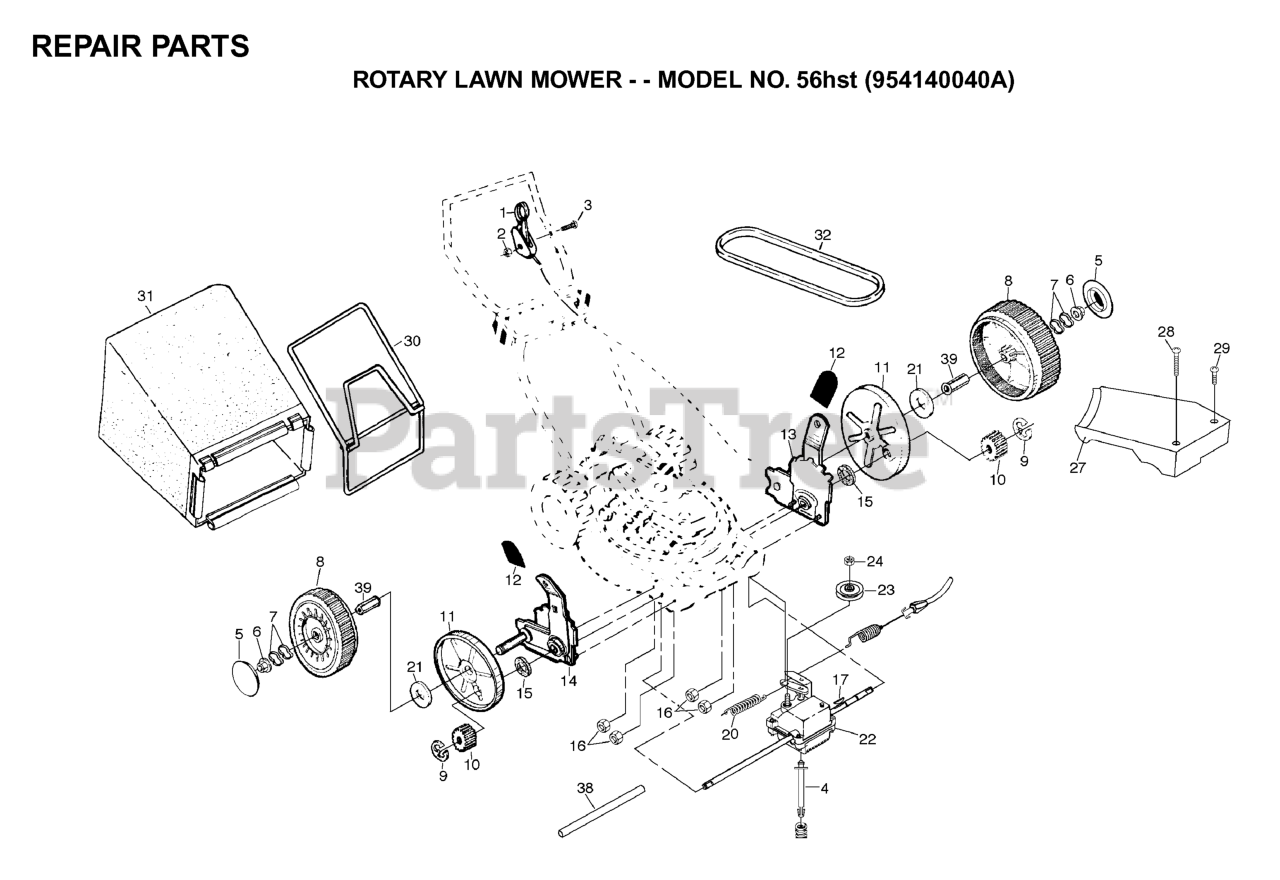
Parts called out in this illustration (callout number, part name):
1	DRIVE CONTROL
2	NUT
3	SCREW 1/4-20 X 2.12
4	SPRING RETAINER
5	HUBCAP.8".GREY
6	HEX FLANGE LOCKNT
7	WAVE WASHER
8	WHEEL & TIRE 8 X 2
9	E-RING 7/16 RE
10	PINION GEAR
11	DUST SHROUD PM
12	SELECTOR KNOB
13	WHEEL ADJUSTER ASSY (LEFT)
14	WHEEL ADJUSTER KIT RH
16	NUT
17	HI PRO KEY PM WSL
18	SPRING.EXTENSION
21	WASHER FLUT
22	GEAR CASE ASMBLY
23	PULLEY
24	FLANGED LOCKNUT 3/8-16 ZINC
27	DRIVE COVER-GRAY
29	SCREW.SLOT.TORX.
30	CATCHER.FRAME.WALK
31	GRASS BAG
32	BELT THERM .32
38	DRV SHAFT TUBE PM
39	BUSHING PM
